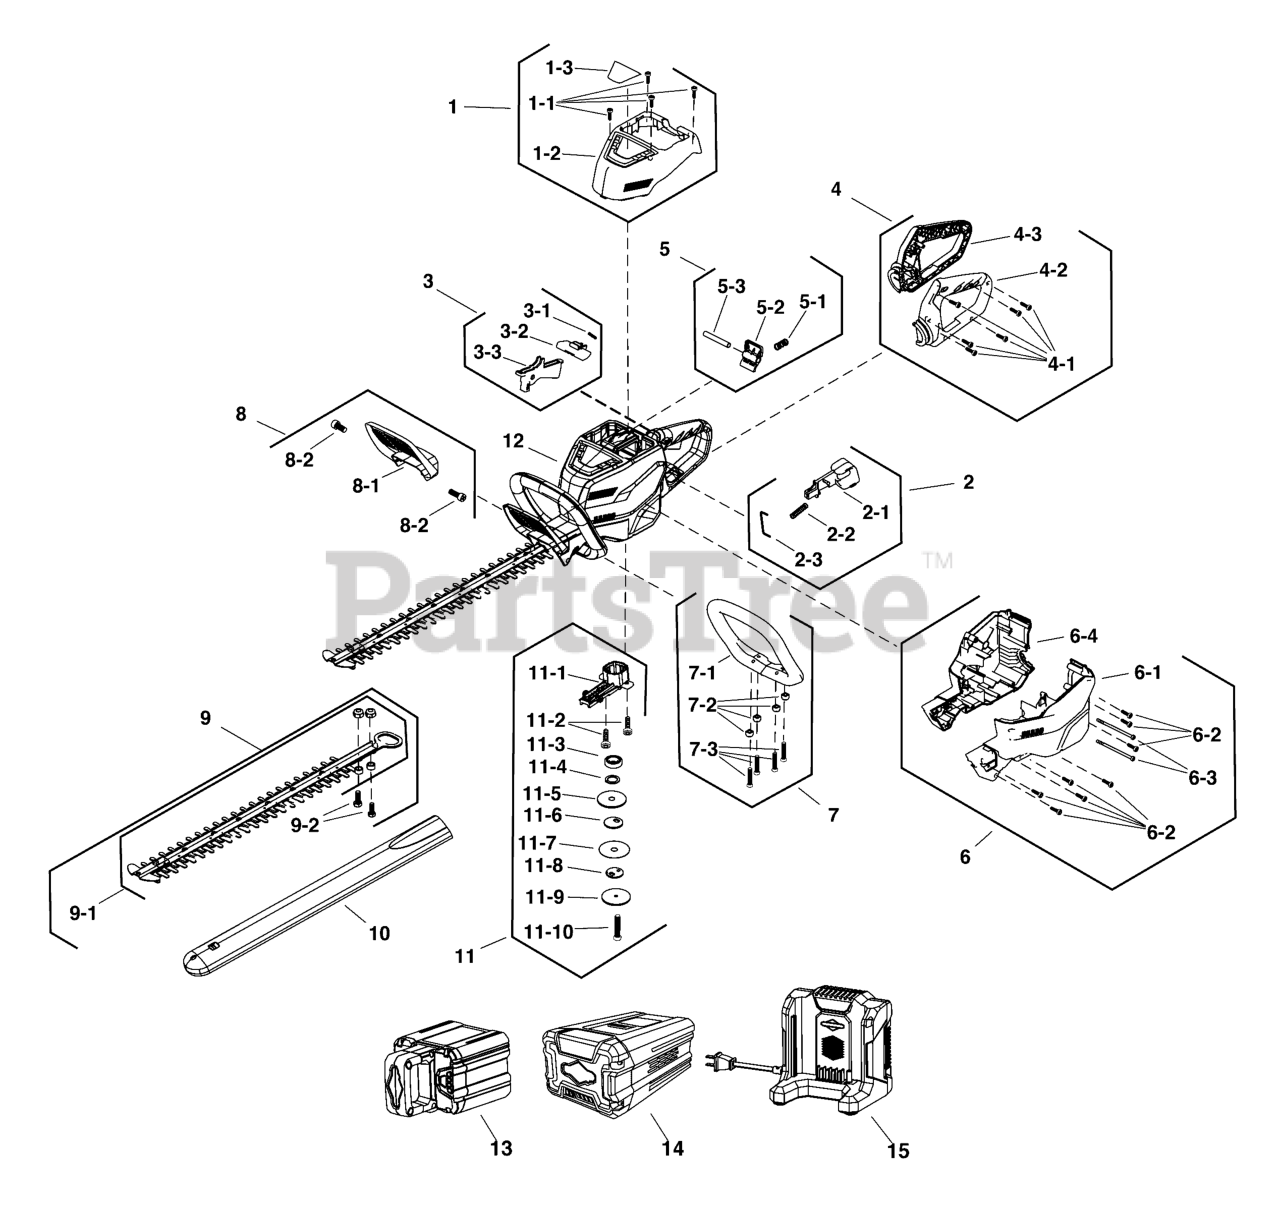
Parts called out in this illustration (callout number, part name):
1	KIT, Top Cover
1-2	COVER, Top
1-3	LABEL, Logo
2	KIT, Latch
2-1	LATCH
2-2	SPRING
2-3	WIRE FORM
3	KIT, Trigger
3-1	SPRING
3-2	BUTTON, Antlock
3-3	TRIGGER
4	KIT, Handle
4-2	HANDLE, Left
4-3	HANDLE, Right
5	KIT, Latch
5-1	SPRING
5-2	LEVER, Release
5-3	PIN
6	HOUSING ASSEMBLY
6-1	COVER, Side, Left
6-4	COVER, Side, Right
7	KIT, Handle
7-1	HANDLE
8	KIT, Guard
8-1	GUARD
9	KIT, Blade
9-1	BLADE ASSEMBLY
10	COVER, Blade
11	KIT, Gear Assembly
11-1	GEAR CASE
11-3	BEARING, Ball
11-6	CAM, Block
11-7	WASHER
11-8	CAM, Block
12	* HEDGE TRIMMER, 48V
13	* BATTERY, 2.0, 48V
14	* BATTERY, 5.0, 48V
15	* BATTERY CHARGER, 48V
